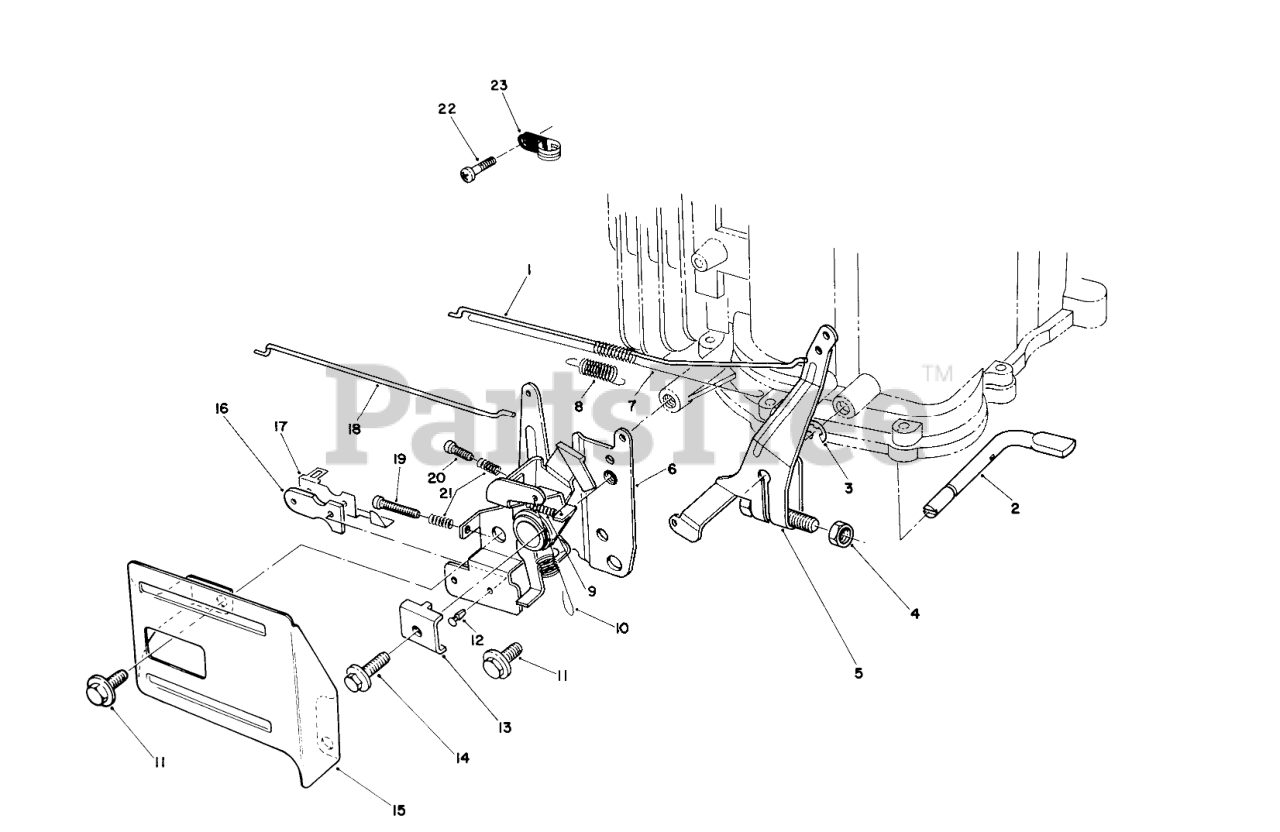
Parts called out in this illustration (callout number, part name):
1	Rod-Carburetor
2	SHAFT
3	E-RING
5	ARM ASM
6	THROTTLE
7	SPRING
8	SPRING
9	SPRING
10	SPRING
12	RIVET
13	CLAMP-CABLE
15	THROTTLE GUARD
16	INSULATOR-KILL SWITCH
17	TERMINAL-KILL SWITCH
18	Rod-Choke
19	SCREW
20	SCREW
21	SPRING
22	SCREW
23	Clamp
